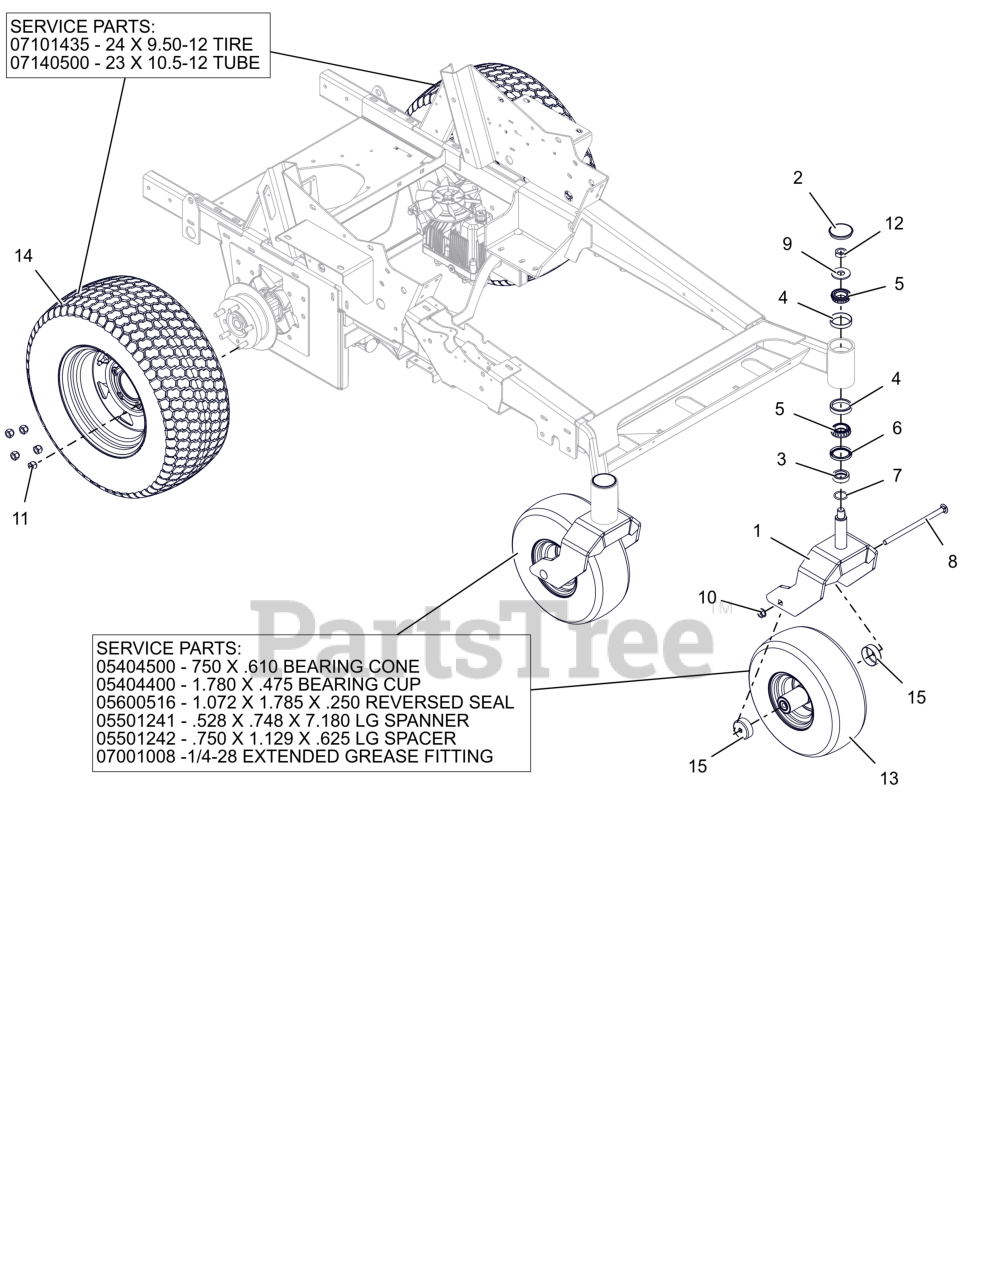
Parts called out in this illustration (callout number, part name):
1	WLDMT, CASTER FORK (RED)
2	CAP, DUST
3	SPCR, FRONT CASTER FORK
4	BRG-CUP 2.328X.465
5	BRG-CONE 1.25X.66
6	SEAL, OIL 1.75 X 2.332 X .312
8	BLT-RHSN .50-13X9.00 G5 ZCC NS
9	WSHR-FL-STL 0.812X2X0.148 ZCC
10	NUT-LK-CTR-FLG .500-13 GG ZCC
11	NUT, WHEEL .50-20 ZCC
12	NUT, JAM-TOPLOCK .750-16 ZCC
13	ASM, TIRE/WHEEL 15 X 6.00-6 SEMI
13	BRG-CONE .750X.61
13	BRG-CUP 1.781X.475
13	SEAL,1.072X1.785X.250 REVERSED
13	SPANNER, .528X.748X7.18 LG
13	SPACER, .750X1.129X.625 LG
13	GREASE FITTING 1/4-28 EXTENDED
14	ASM-WHL/TIRE24X9.5-12 RAD BK
14	TIRE- 24 X 9.50-12 RADIAL
14	TUBE 22,23&24X8.50/9.50/10.00/10.50/12.00-12
15	SHIELD, WHEEL BEARING
